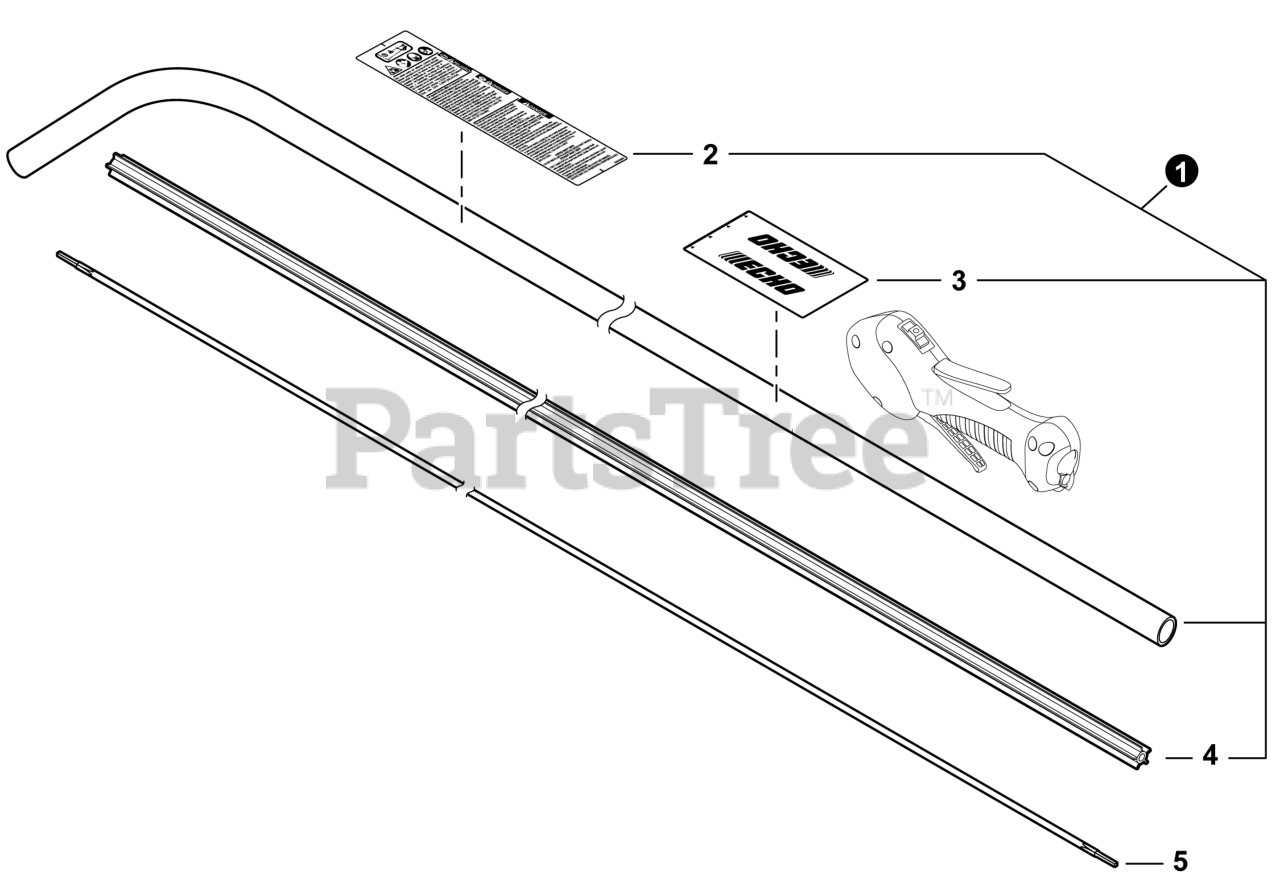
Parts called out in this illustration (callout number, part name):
1	MAIN PIPE ASSY
2	LABEL - CAUTION
3	LABEL - HANDLE LOCATION
4	LINER - FLEXIBLE
5	DRIVESHAFT - FLEXIBLE
